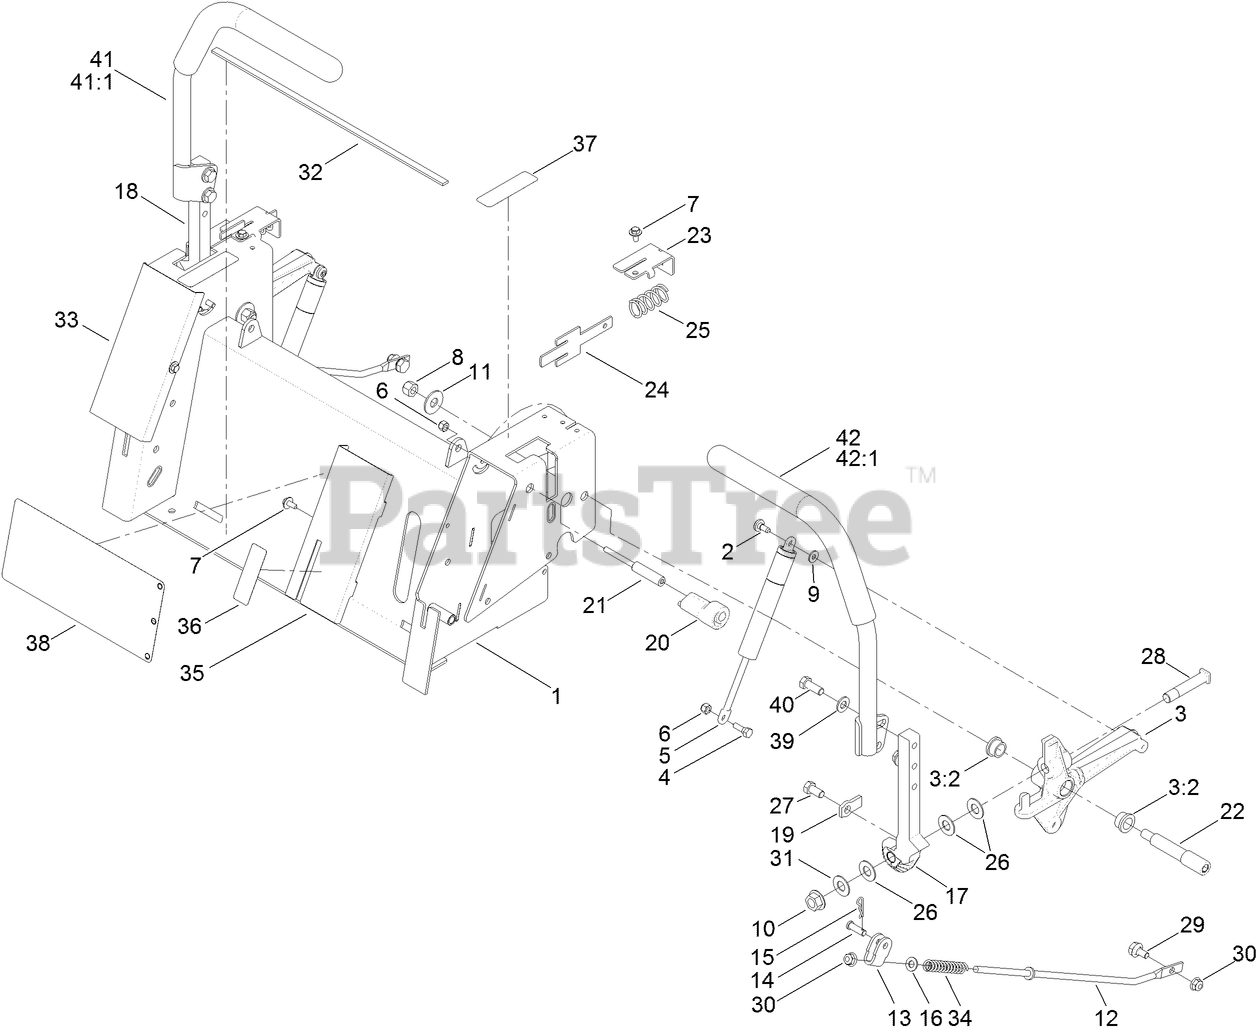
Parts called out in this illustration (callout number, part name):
1	BOX-CONTROL
2	SCREW-SHOULDER
3	ACTIVATOR ARM ASM
3:2	BUSHING
4	BOLT-SHOULDER
5	DAMPER-CONTROL, MOTION
6	NUT-LOCK, NI
7	SCREW-HHFTF
8	NUT-LOCK, NI
9	WASHER
10	NUT-HF
11	WASHER-FLAT
12	ROD-CONTROL
13	BRACKET-CONTROL
14	PIN-CLEVIS
15	PIN-COTTER
16	WASHER-PLAIN
17	ARM-ACTUATOR, LH
18	ARM-ACTUATOR, RH
19	TAB-STOP
20	ECCENTRIC
21	SCREW-ECCENTRIC
22	BOLT-SHOULDER
23	BRACKET-RETURN
24	PLATE-RETURN
25	SPRING-COMPRESSION
26	WASHER-PIVOT
27	SCREW-HH
28	BOLT-SHOULDER
29	BOLT-SHOULDER,HFH
30	NUT-HF, NI
31	WASHER-TEFLON
32	STRIP-VIBRATION, ANTI
33	COVER-CONTROL, RH
34	SPRING-RETURN, NEUTRAL
35	COVER-CONTROL, LH
36	DECAL-BRAKE, PARKING
37	DECAL-CONTROL, MOTION
39	WASHER-FLAT
40	SCREW-HH
41	RH LEVER/GRIP ASM
41:1	GRIP-CONTROL, MOTION
42	LH LEVER/GRIP ASM
42:1	GRIP-CONTROL, MOTION
